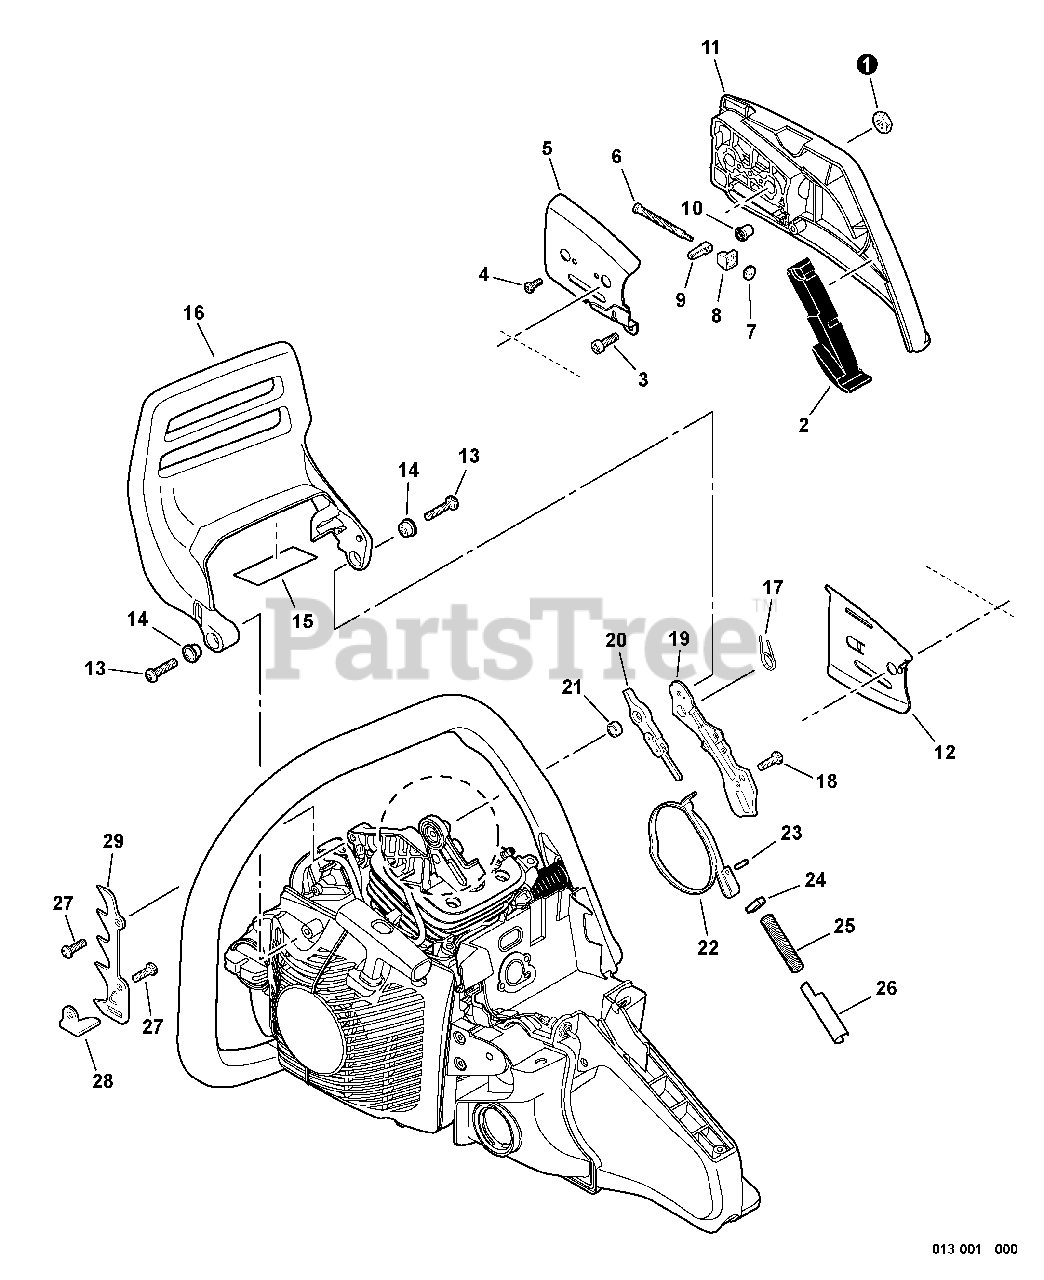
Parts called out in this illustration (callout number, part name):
2	CUSHION
3	BOLT, TORX 4×12
4	SCREW 3×5
5	PLATE, GUIDE - OUTER
6	SCREW, CHAIN TENSION
7	GEAR, BEVEL
8	COLLAR 8
9	TENSIONER, CHAIN
10	GEAR, BEVEL
11	GUARD, SPROCKET
12	PLATE, GUIDE - INNER
13	BOLT, TORX 5×16
14	COLLAR 11.2×16.2×T0.6
15	SHIELD, HEAT
16	LEVER, BRAKE
17	SPRING, TORSION
18	BOLT, TORX 5×16
19	COVER, BRAKE
20	CONNECTOR, BRAKE
21	SPACER 12×10×T: 1.0
22	BAND, BRAKE
25	SPRING, COMPRESSION Ø12×70.5
26	PLATE, SIDE
27	BOLT, TORX 5×16
28	CHAIN CATCHER
29	SPIKE, BUMPER
